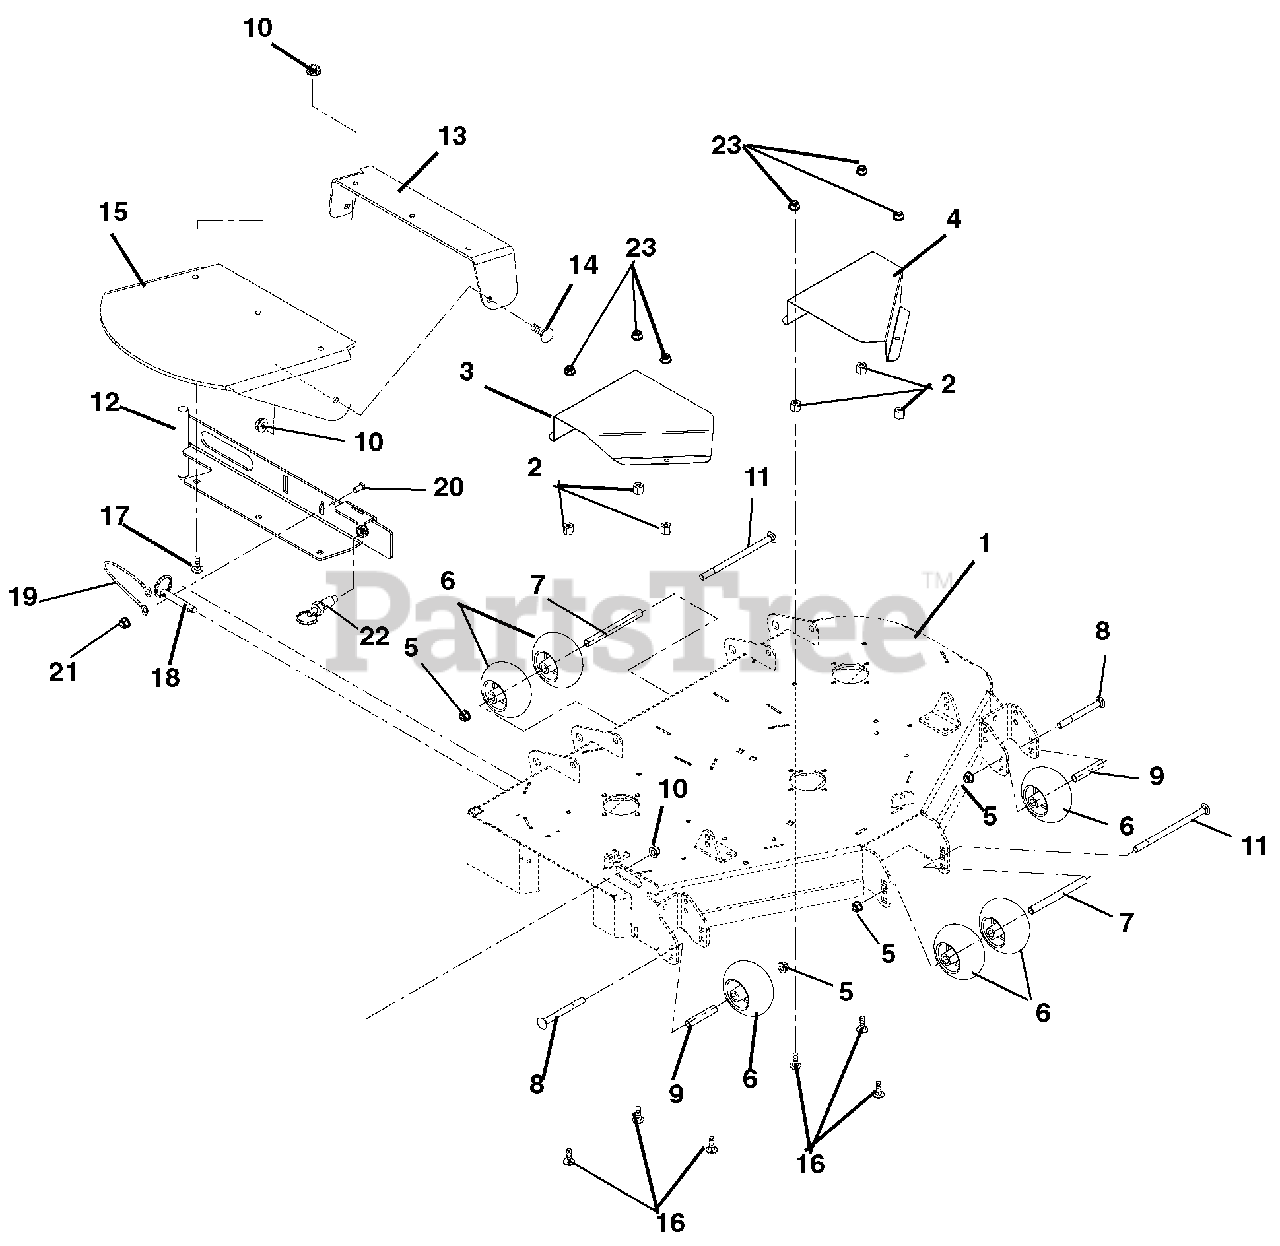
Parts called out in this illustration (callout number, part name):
1	44" Side Discharge Deck Weldment
1	48" Side Discharge Deck Weldment
2	Nut, Heavy Hex .38-16
3	Guard, 44-52 RH Spindle Sheave
4	Guard, 44-52 LH Spindle Sheave
5	Nut .50-13 Nyloc Flange
6	Anti-Scalp Wheel
8	Bolt, Round Head Square Neck .50-13 x 5.00
9	Spacer, .510 x .625 x 3.35
10	Nut, .38-16 Nyloc Flange
11	Bolt, Round Head Square Neck .50-13 x 8.50
12	Weldment, Discharge Chute Support
13	Rubber Discharge Chute Support
14	Bolt, Round Head Square Neck .38-16 x 1.00 Grade 5
15	Chute, Rubber Discharge
16	Bolt, Hex Head .38-16 x 1.25 Grade 5
17	Bolt, Round Head Square Neck .38-16 x 1.25 Grade 5
18	Pin, Spring Ball .375 x 1.50
19	Cable, 6.0 Lanyard
20	Bolt, Hex .25-20 x .75
21	Nut, Locking Top Flange .25-20
22	Pull Pin
23	Nut, Flange .375-16
